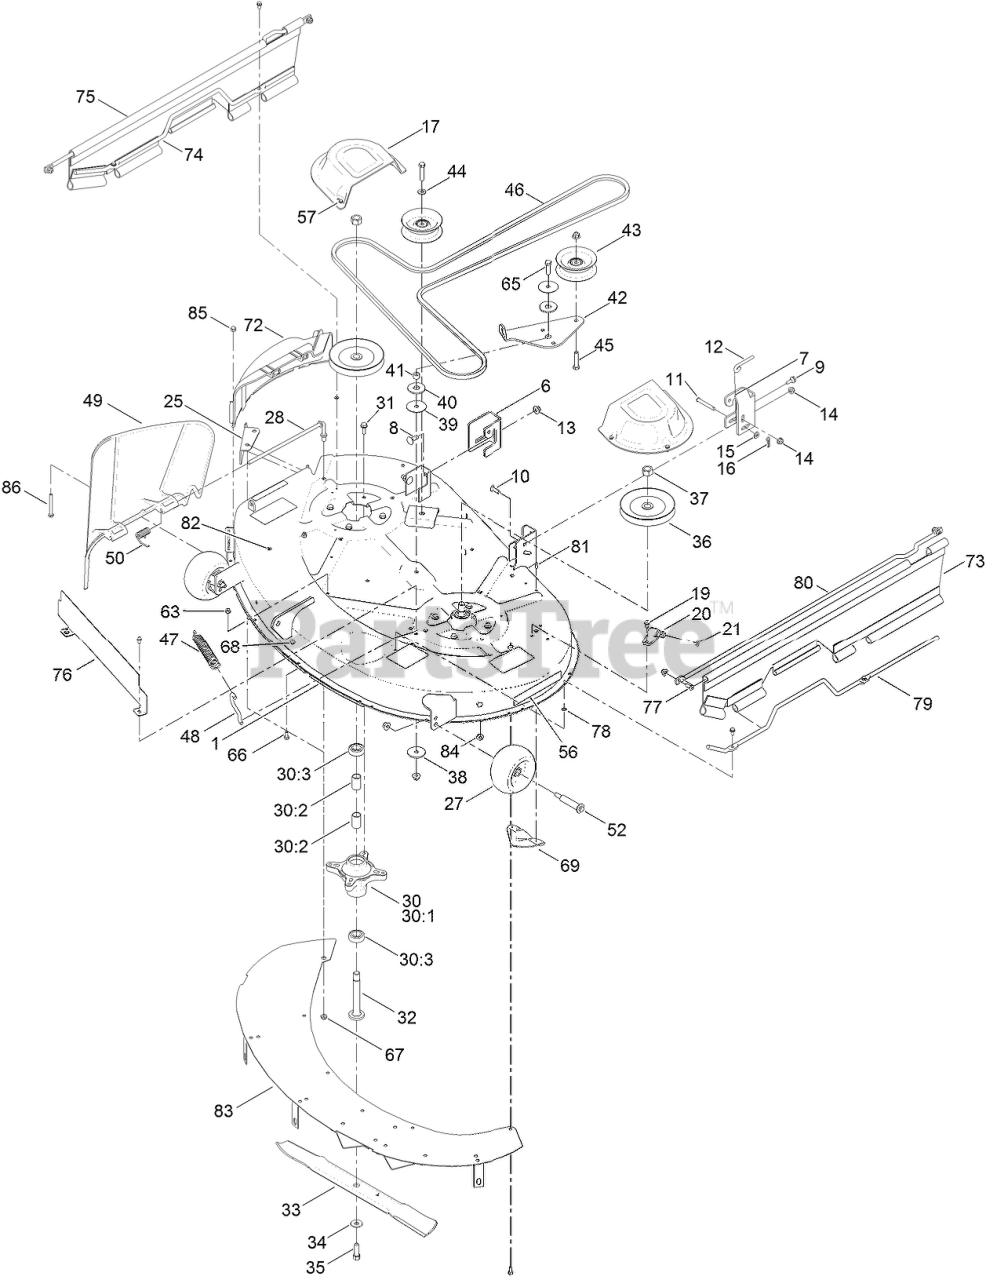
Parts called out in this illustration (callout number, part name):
1	42 INCH DECK AND DECAL ASM
6	BRACKET-HANGER, RH
7	BRACKET-HANGER, LH
8	BOLT-CARR
9	SCREW-SHOULDER, HHF
10	SCREW-CARR
11	PIN-CLEVIS
12	ROD-LEVEL, DECK
13	NUT-HF, NI
14	NUT-HF, NI
15	WASHER-PLAIN
16	PIN-COTTER
17	COVER-BELT
19	SCREW-HWH
20	FITTING-WASHOUT
21	O-RING
25	BAFFLE-CUTOFF
27	ROLLER-SCALP, ANTI
28	ROD-PIVOT
30	SPINDLE ASM
30:1	SPINDLE
30:2	SPACER
30:3	BEARING-BALL
31	SCREW-TAPTITE
32	SHAFT-SPINDLE
34	WASHER-BELLEVILLE
35	SCREW-HH
36	Pulley
37	NUT-HEX
38	WASHER-REBOUND
39	WASHER
40	WASHER-FRICTION, COMPOSITE
41	SPACER
42	ARM-IDLER
43	PULLEY-IDLER, FLAT
44	WASHER-FLAT
45	SCREW-HH
46	V-BELT
47	SPRING-EXTENSION
48	HOOK-RETURN, SPRING
49	DEFLECTOR
50	SPRING-TORSION
52	BOLT-SHOULDER
56	DECAL-RECYCLER
57	SCREW-TAPTITE
63	NUT-LOCK, NI
65	SCREW-HH
66	SCREW-HH
67	NUT-LOCK, NI
68	SCREW-HH
69	PLATE-KICKER
72	COVER-DISCHARGE
73	ROD-SUPPORT, UPPER
74	ROD-SUPPORT, LOWER (RH)
75	RH GUARD SIDE
76	SHIELD-FRONT, DECK
77	SCREW-HSBH
78	NUT-RETAINING
79	ROD-SUPPORT, LOWER (LH)
80	GUARD-SIDE, LH
81	SCREW-PPH
82	NUT-RETAINING
83	BAFFLE UPPER ASM
84	NUT-HF
85	NUT-CAP
86	SCREW-HH
